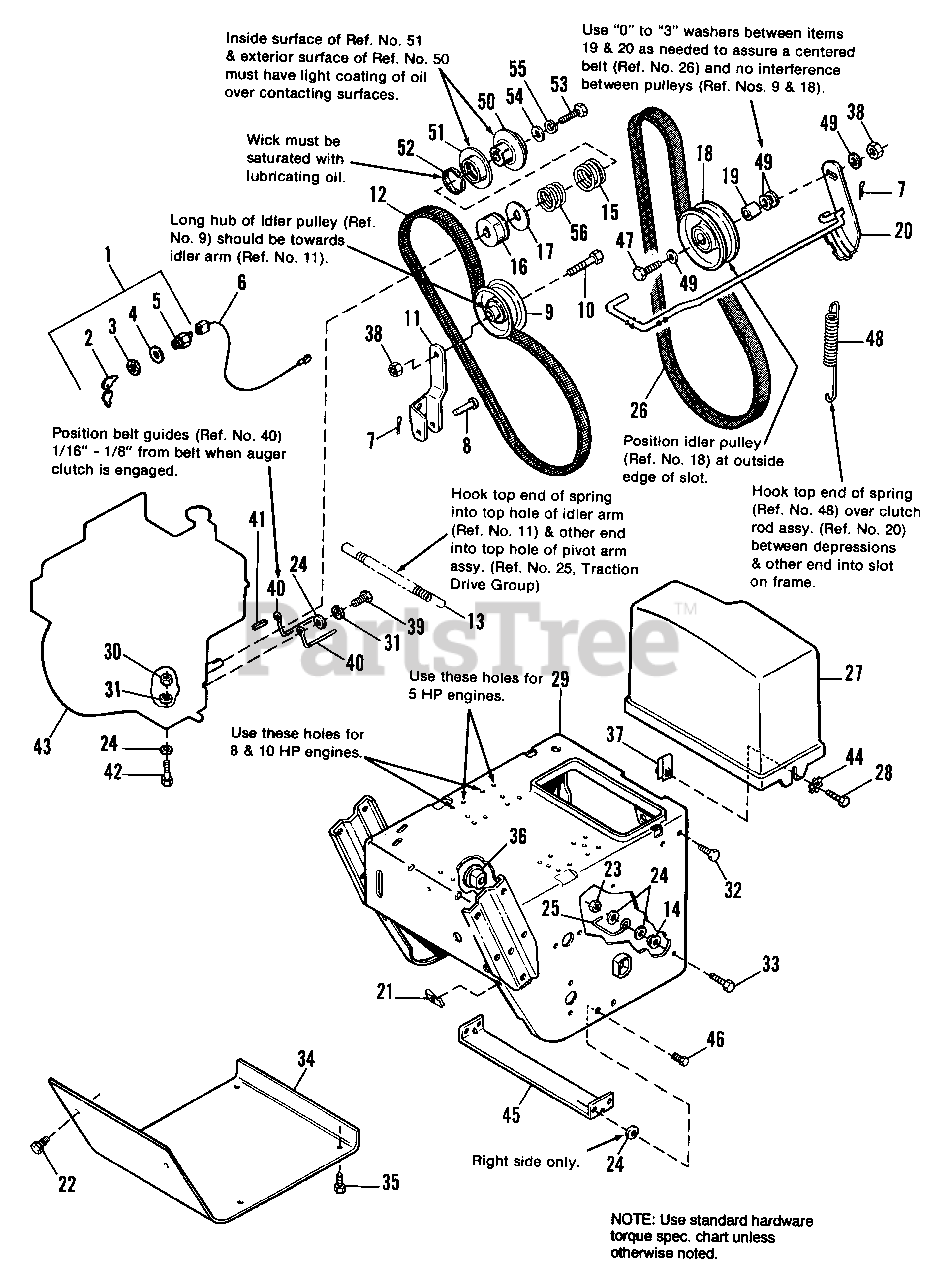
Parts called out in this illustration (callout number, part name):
1	SWITCH, Key (Inc. Ref. Nos. 2, 3, 4 & 5)
3	NUT, Hex, 5/8-32
4	LOCKWASHER, Int. 5/8
6	WIRE, Ground
7	PIN, Cotter, 1/8 x 3/4
8	PIN
9	PULLEY, Idler
10	CAPSCREW, Hex Hd., 3/8-16 x 1-3/8
11	ARM, Idler, Traction
12	BELT, Traction
13	SPRING, Idler
14	NUT, Hex, Whizlock, 5/16-18
15	SPRING, Compression (all models except 1691774)
16	PULLEY, Traction
17	WASHER, Thrust
18	PULLEY ASSY.
20	CLUTCH ROD & BRAKE ASSY.
21	NUT, Speed, 1/4-20
22	SCREW, Taptite, 1/4-20 x 5/8
23	NUT, Hex, Centerlock, 5/16-18
24	WASHER, 11/32 x 3/4
26	BELT, Auger Drive
27	GUARD, Belt
28	SCREW, Truss Hd., 5/16-18 x 3/4
29	FRAME, Main (1691774 Only)
29	FRAME, Main (all models except 1691774)
30	NUT, Hex, 5/16-18
31	LOCKWASHER, 5/16
32	CAPSCREW, Whizlock, 5/16-18 x 3/4
33	CAPSCREW, Whizlock, 5/16-18 x 1-1/4
34	COVER, Bottom
35	SCREW, Taptite, 1/4-20 x 3/8
36	BUSHING, Axle
37	NUT, Speed, 5/16-18
38	LOCKNUT, Jam, 3/8-16
39	CAPSCREW, Hex. Hd., 5/16-24 x 3/4
40	BELT GUIDE
41	KEY, Parallel, 3/16 x 13/16 x 7/8
42	CAPSCREW, Hex Hd., 5/16-18 x 2
43	ENGINE, Tecumseh, 5 H.P.
43	ENGINE, Tecumseh, 8 H.P. (with manual start & light coil)
43	ENGINE, Tecumseh, 10 H.P. (with manual start & light coil)
43	ENGINE, Tecumseh,10 H.P. (with 7 amp charge circuit)
44	LOCKWASHER, Ext. Tooth, 5/16
45	SUPPORT, Tie Bar
46	SCREW, Taptite, 5/16-18 x 3/8 (left side only)
47	CAPSCREW, Hex Hd., 3/8-16 x 1-3/4
48	SPRING, Extension
49	WASHER, Flat, 13/32
50	PULLEY, Half, Drive
51	PULLEY, Half
53	CAPSCREW, Hex Hd., 3/8-24 x 2
54	WASHER, 13/32 x 1
55	LOCKWASHER, Spring, 3/8
56	SPRING, Compression (1691776, 1691779, 1691899, 1691948)
56	SPRING, Compression (1691774, 1691775, 1691898)
